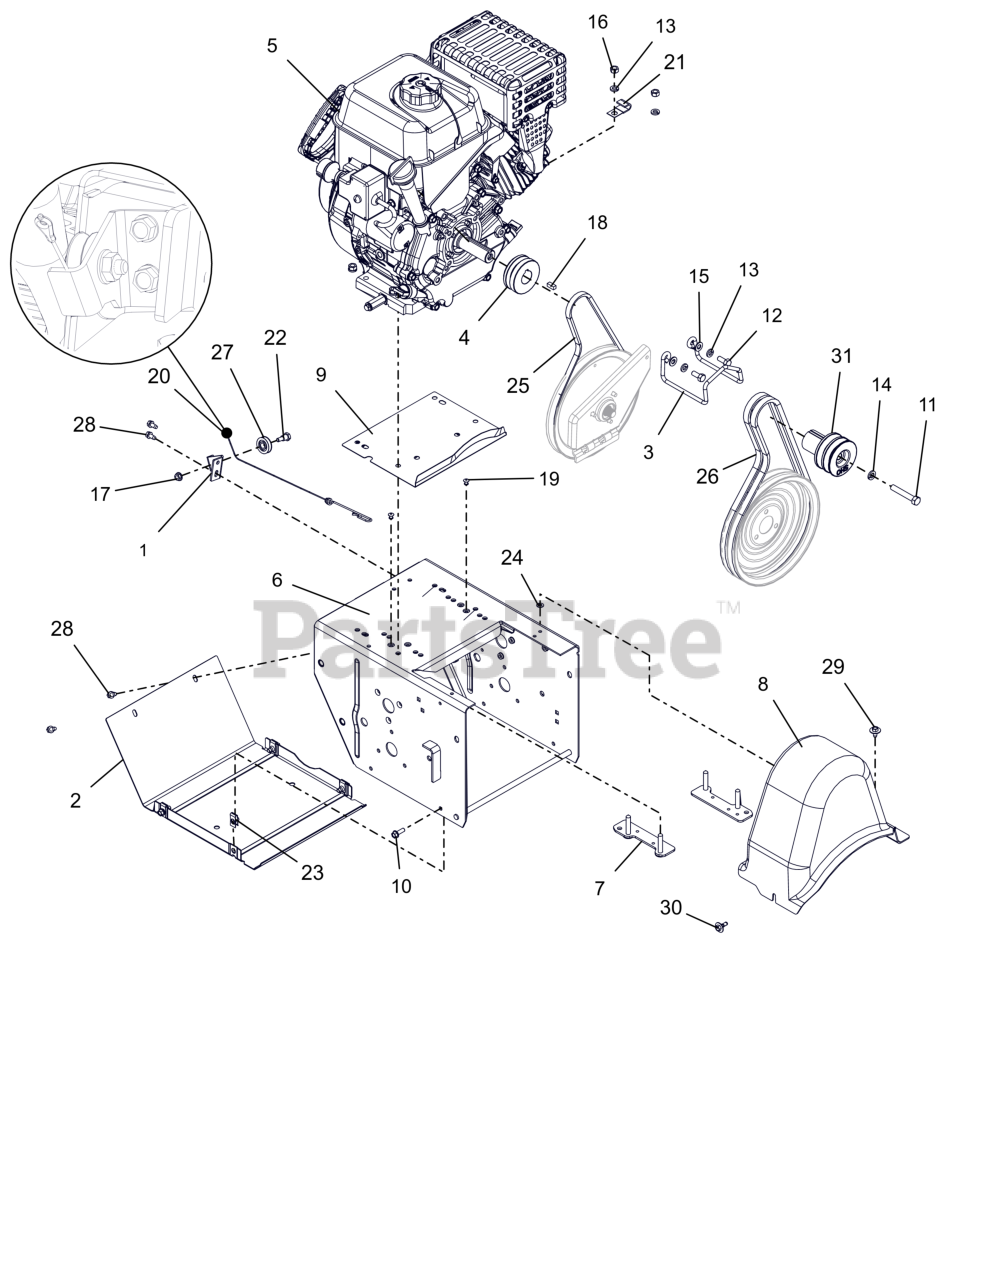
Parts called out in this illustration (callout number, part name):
1	BRACKET, CABLE PULLEY
2	COVER, BOTTOM
3	FINGER, BELT
4	SHEAVE, DRIVE
5	ENGINE, ARIENS AX291 240V/60W
6	FRAME, MAIN-DELUXE(WELDMENT)
7	STRAP, ENGINE-MEDIUM BLOCK
8	COVER, BELT-LARGE
9	BAFFLE, WATER - LARGE BLOCK
10	BLT, HWH .25-20X.75 G5 ZCC
11	BLT, HEX .38-24X2.25 G5 ZCC
12	BLT, HEX .31-24X.750 G5 ZCC
13	WSHR, LK-HVY .312X.097 ZCC
14	WSHR,LK-REG .375X.094 ZCC
15	WSHR,FLT .344X.688X.065 ZCC
16	NUT, HEX .312-18 ZCC
17	NUT-LK-TOP-FLG .250-20 GF ZCC
18	KEY-SQ .25X.625X.25 SAE 8630
19	RVT, POP .1875 ZCC
20	CABLE, LOWER TRACTION,SS & PRO
21	J-CLAMP
22	BOLT, SHLDR -.375 X .375 X .25-20
23	NUT-RTNR .25-20X.56
24	NUT-PUSH .25X.50 O.D.
25	V-BELT, 3L-WRAPPED
26	V-BELT, HA-RAW EDGE (SET)
27	PULLEY, CABLE
28	SCR-TAP .25-20X.50 HWH ZCC
29	SCR, TAP .25-20X.50 LG HWH ZCC
30	SCR-TAP .25-20X.5 CAPTIVE
31	SHEAVE,ATTACHMENT-SHO 2 GRV
